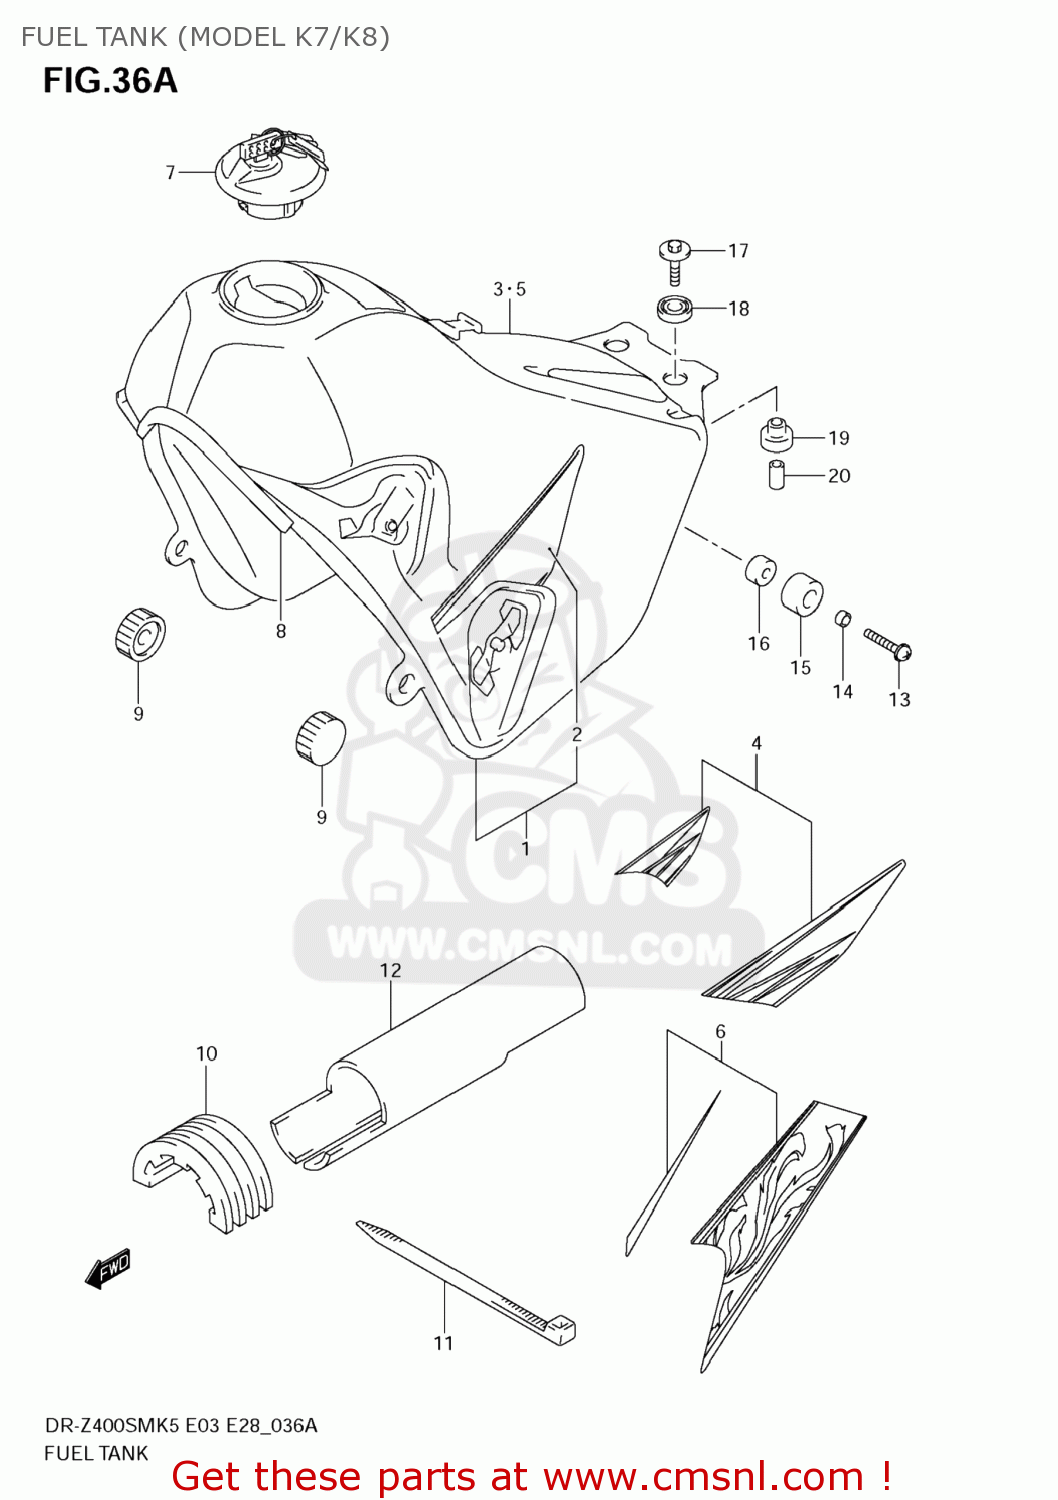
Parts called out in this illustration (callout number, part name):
1	TANK ASSY,FUEL(YELLOW)
2	TAPE SET,FUEL TANK
3	TANK ASSY,FUEL(BLUE)
4	TAPE SET,FUEL TANK
5	TANK ASSY,FUEL(BLACK)
6	TAPE SET,FUEL TANK
7	CAP SET,FUEL TANK
8	MOLDING
9	CUSHION
10	CUSHION,FUEL TANK
11	CLAMP(L:300)
12	SHIELD,FUEL TANK
13	SCREW
14	SPACER(6.5X20X9)
15	CUSHION
16	SPACER(6.5X9X5)
17	BOLT(6X30)
18	CUSHION
19	CUSHION
20	SPACER(6.5X9X18)
